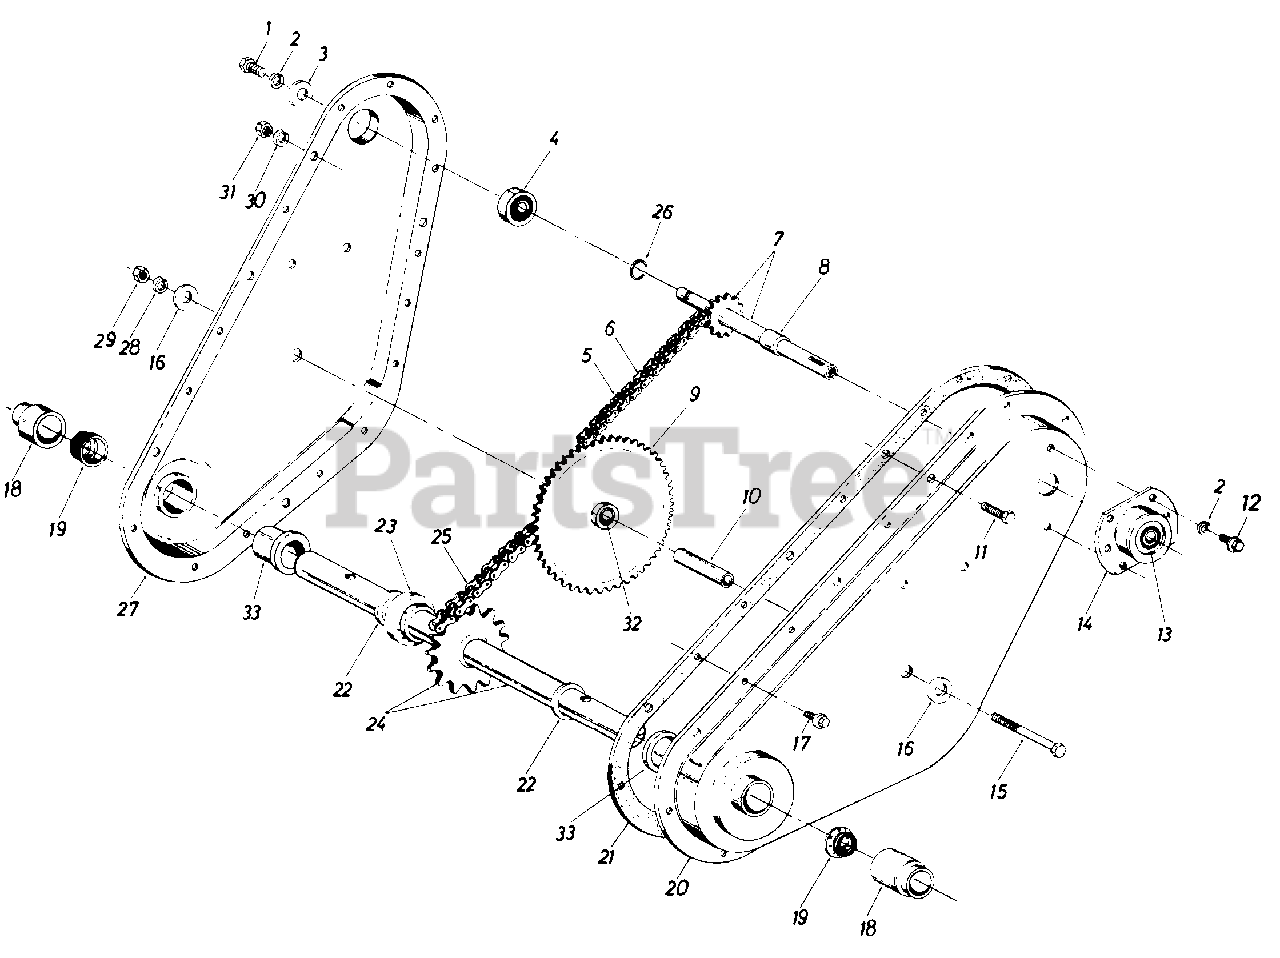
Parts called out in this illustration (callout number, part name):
1	Hex L-Scr. 1/4-28 x .625" Lg.
2	L-Wash. 1/4" Scr.
3	Fl-Wash. .25" I.D. x .93" O.D. x .125" Thk.
4	Bearing .62" I.D. x 1.38" O.D. x .437" Thk.
5	#35 Chain 3/8 Pitch x 52 Links Endless
6	Master Link
7	Input haft Assembly
8	Spacer
9	Sprocket Assembly
10	Sprocket Hub Tubing 818n l.D. x 5/8" O.D. x 1.9" Lg.
11	Hex Scr. 5/16-18 x .625" Lg.
12	Hex Wash. Hd. Self-Tap Scr. 1/4-20 x .50" Lg.
13	Bearing .625n l.D. x 1.38" O.D. x .437" Thk.
14	Bearing Housing
15	Hex Scr. 3/8-24 x 2.75" Lg.
16	Fl-Wash. 3/8 I.D. x 1.25" O.D. x .100 Thk.
17	Hex Wash. Hd. Self-Tap Scr. 1/4-20 x .50" Lg.
18	Dust Cap
22	Thrust Wash. 1.00" I.D. x .030" Th k.
23	Step Spacer
24	Tine Shaft Assembly
25	#50 Chain 5/8" Pitch x 46 Links Endless
26	Snap Ring 5/8" Dia. Shaft
29	Hex Nut 3/8-24 Thd.
30	L-Wash. 5/16" Scr.
31	Hex Nut 5/16-18 Thd.
32	Bearing
33	Bearing
